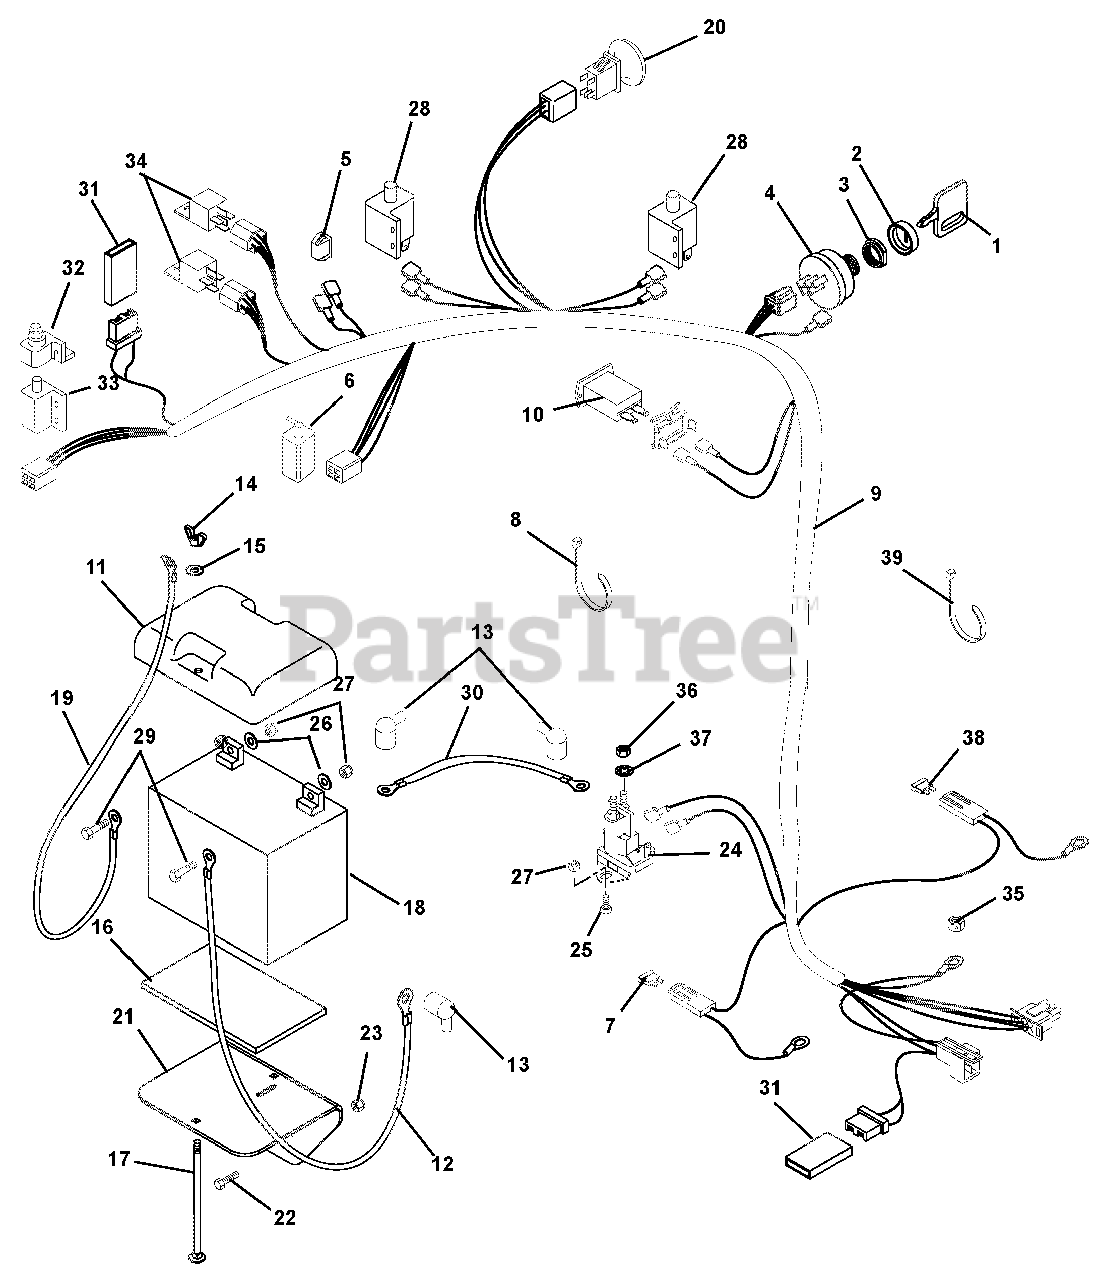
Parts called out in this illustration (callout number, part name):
1	Key, with Cap
2	Cap, Ignition Switch
3	Nut, Panel .625-32
4	Key Switch
5	Light, Indicator (126, 127)
6	Switch, Double Pole N.O./N.O. (108, 123, 126)
7	Fuse, 25 AMP
8	Tie Wrap, Black
9	Wire Harness (108, 123, 126)
10	Hour Meter, Quartz
11	Cover, Battery
12	Cable, Positive Battery
13	Boot, Eyelet Terminal
14	Nut, Locking-Wing .25-20
15	Washer, Flat-Steel .281 x .625 x .065
16	Pad, Battery
17	Bolt, Round Head Square Neck .25-20 x 7.50 Grade 2
19	Cable, Negative Battery
20	Switch, Clutch With Retainer
21	Weldment, Battery Tray
22	Bolt, Hex .38-16 x 1.75 Grade 5
23	Nut, Locking-Nylon .38-16
24	Solenoid
25	Bolt, Hex .25-20 x .50 Grade 5
26	Washer, Flat-Steel .281 x .62 x .065
27	Nut, Locking-Flange .25-20
28	Switch, Single Pole (N.O.)
29	Bolt, Hex .25-20 x .75 Grade 5
30	Starter Cable 6.75"
31	Diode, Connector Shell
32	Boot, Rubber
33	Switch, Interlock
34	Relay (108, 123, 126)
35	Nut, Locking-Top-Flange .31-18
36	Nut, Jam .31-24
37	Washer, Locking .31
38	Fuse, 20 AMP
39	Tie Wrap
